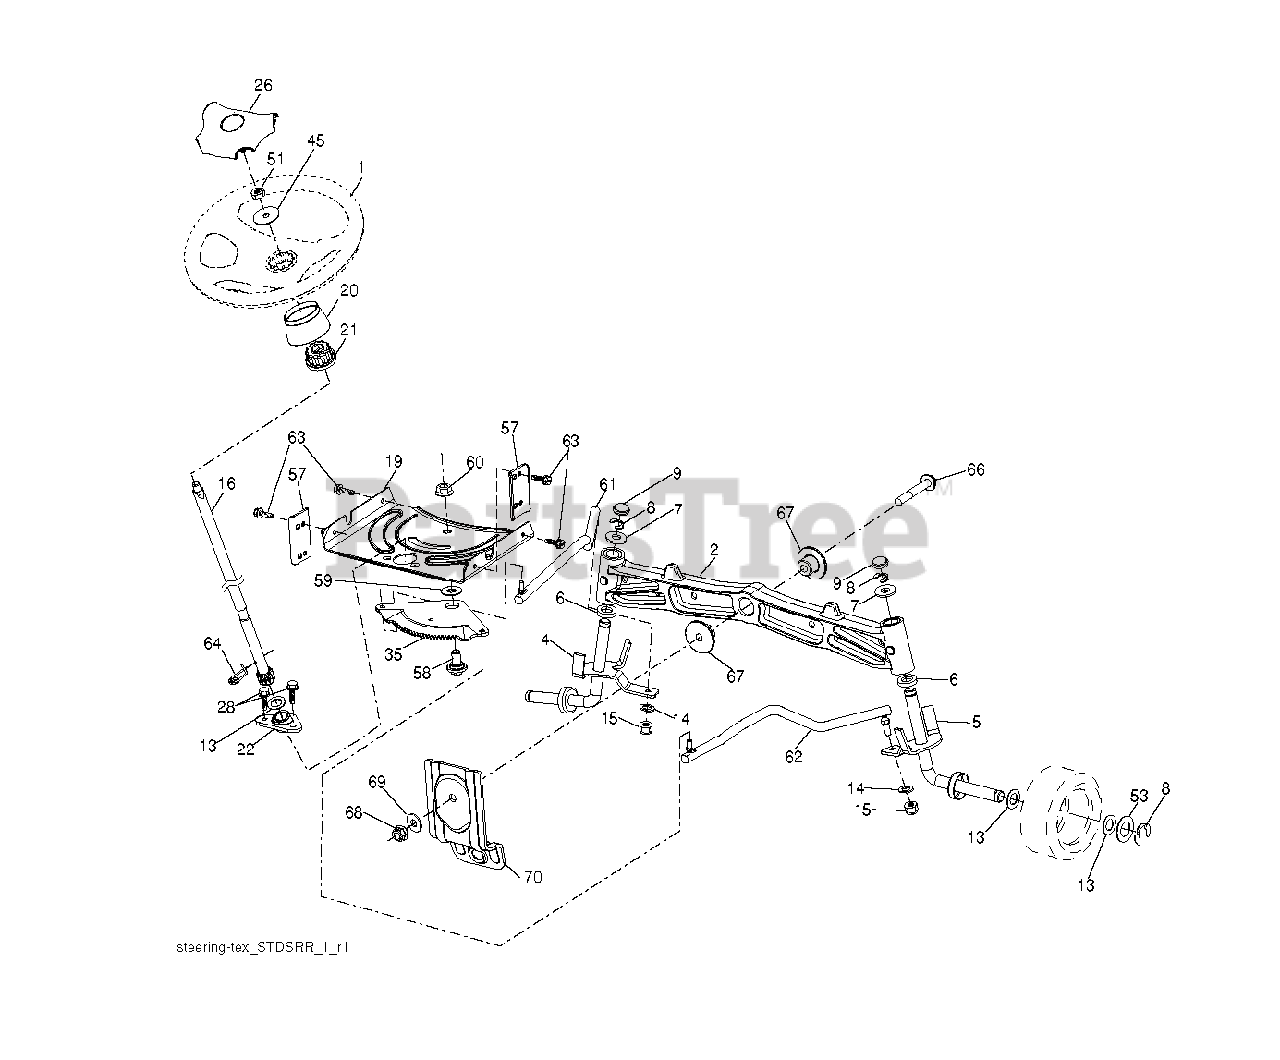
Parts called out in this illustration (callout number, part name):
1	WHEEL.STEERING.MLT.BR.YEL/OVRM
2	AXLE.CAST.IRON
4	SPINDLE.WELDED.LH.15"TEX
5	SPINDLE.WELDED.RH.15"T
8	RING CLIP
9	CAP.SPINDLE.BLACK
14	WASHER, LOCK 3/8
15	NUT CROWNLOCK 3/8-24
16	SHAFT, STEERING
19	PLATE.STEER.DDL.NLT/NG
20	BOOT, STEERING
21	ADAPTER, WHEEL STNG..
22	STEERING.SUPT.LOWER.
26	CAP.WHL.STRNG.MULTI.BRND.YEL
28	SCREW, 3/8-16X3/4
35	GEAR.SECTOR.PLATE.DDL.
45	WASHER 9/16"ID, 2 3/8""OD
51	NUT.HEX.1/2-20
53	WASHER.HARDENED
57	BRACKET.UPSTOP.TEX
58	BOLT.SHOULDER.SECTOR.P
59	WASHER.THURST.SECTOR.S
60	NUT FLANGE LOCK 5/8-11
61	DRAGLINK.LH.BALLSTUD.D
62	DRAGLINK.RH.BALLSTUD.D
63	SCREW
64	RETAINER.CLIP.SPRING.S
66	BOLT HEX FGHD 7/16-14 X 3 SERR
67	BUSHING.PM.FRONT AXLE
68	NUT.LOCK.FLANGE.7/16
69	WASHER.1.5X.505X.118
70	BRKT.DECK.SUSPENSION.F
